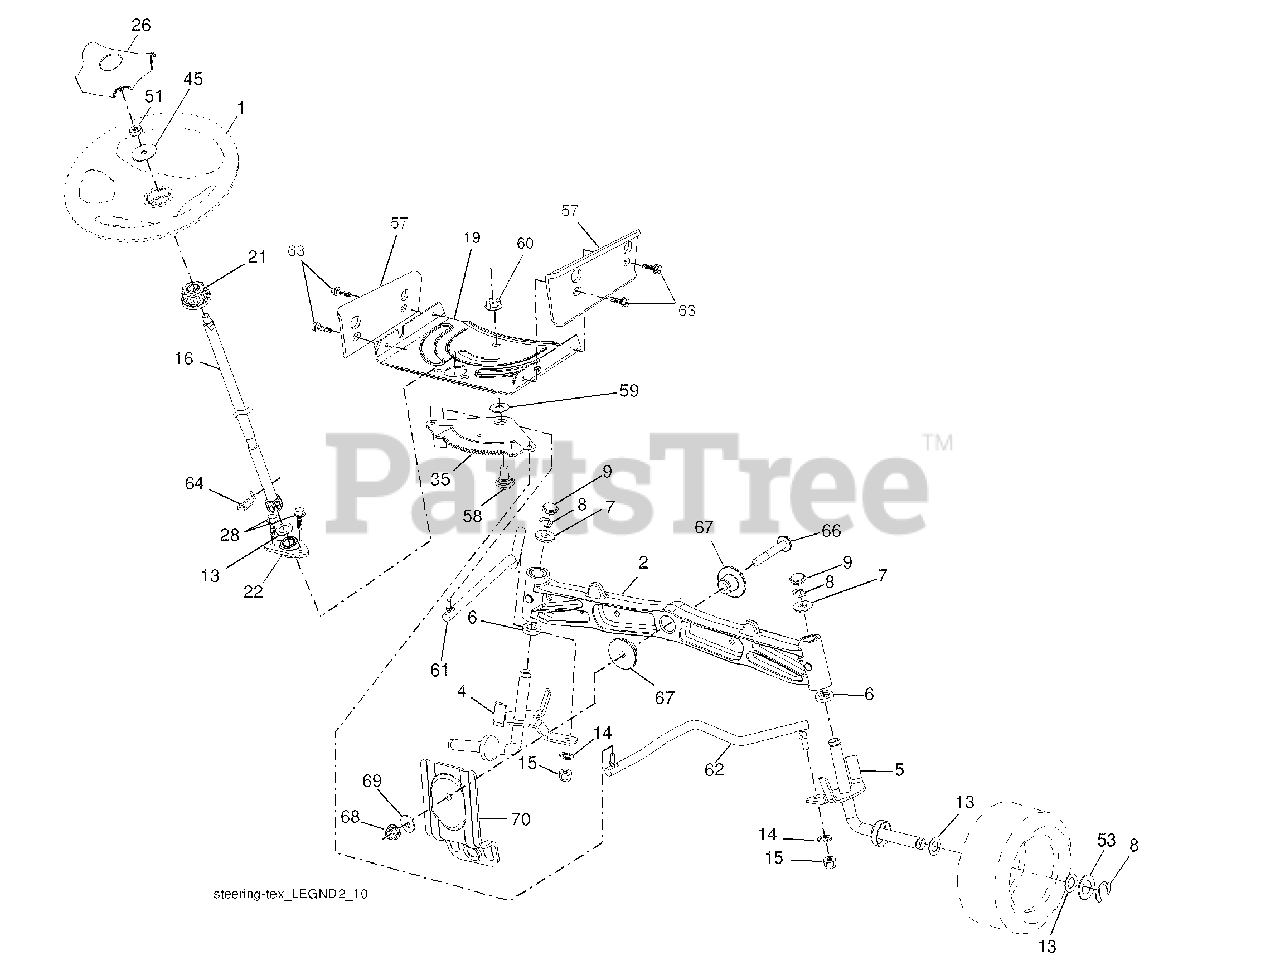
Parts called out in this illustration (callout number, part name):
1	Wheel, Steering
2	Axle Asm., Front
4	Spindle Asm., LH
5	Spindle Asm., RH
6	Bearing, Race Thrust Harden
7	Washer 25/32 x 1-5/8 x 16 Ga.
8	Ring, Klip #T5304-75
9	Cap, Spindle
13	Washer 25/32 x 1-1/4 x 16 Ga.
14	Washer, Lock Hvy Hlcl Spr 3/8
15	Nut, Crown Lock 3/8-24 unf
16	Shaft Steering
19	Plate Steering
21	Adapter, Wheel Steering
22	Bushing, Strg. Blk
26	Insert, Wheel Steering
28	Screw 3/8-16 x 3/4
35	Gear, Sector Plate
45	Washer 9/16 x 2-3/8 x 12 Ga.
51	Nut Hex Jam Toplock 1/2-20 unf
53	Washer Hardened .793 x 1.637 x .060
57	Bracket Upstop
58	Bolt Shoulder Sector Pivot CFM
59	Washer Thrust Sector Steering
60	Nut Flange Lock 5/8-11
61	Draglink LH
62	Draglink, RH
63	Screw 5/16-18 x 3/4
64	Retainer Clip Spring Steering
66	Bolt Hex Fghd 7/16-14 x 3 Serr
67	Bushing PM Front Axle
68	Nut Lock Flange 7/16-14 Gr. 5
69	Washer 1.5 x .505 x .118
70	Bracket Deck Susp. Front
